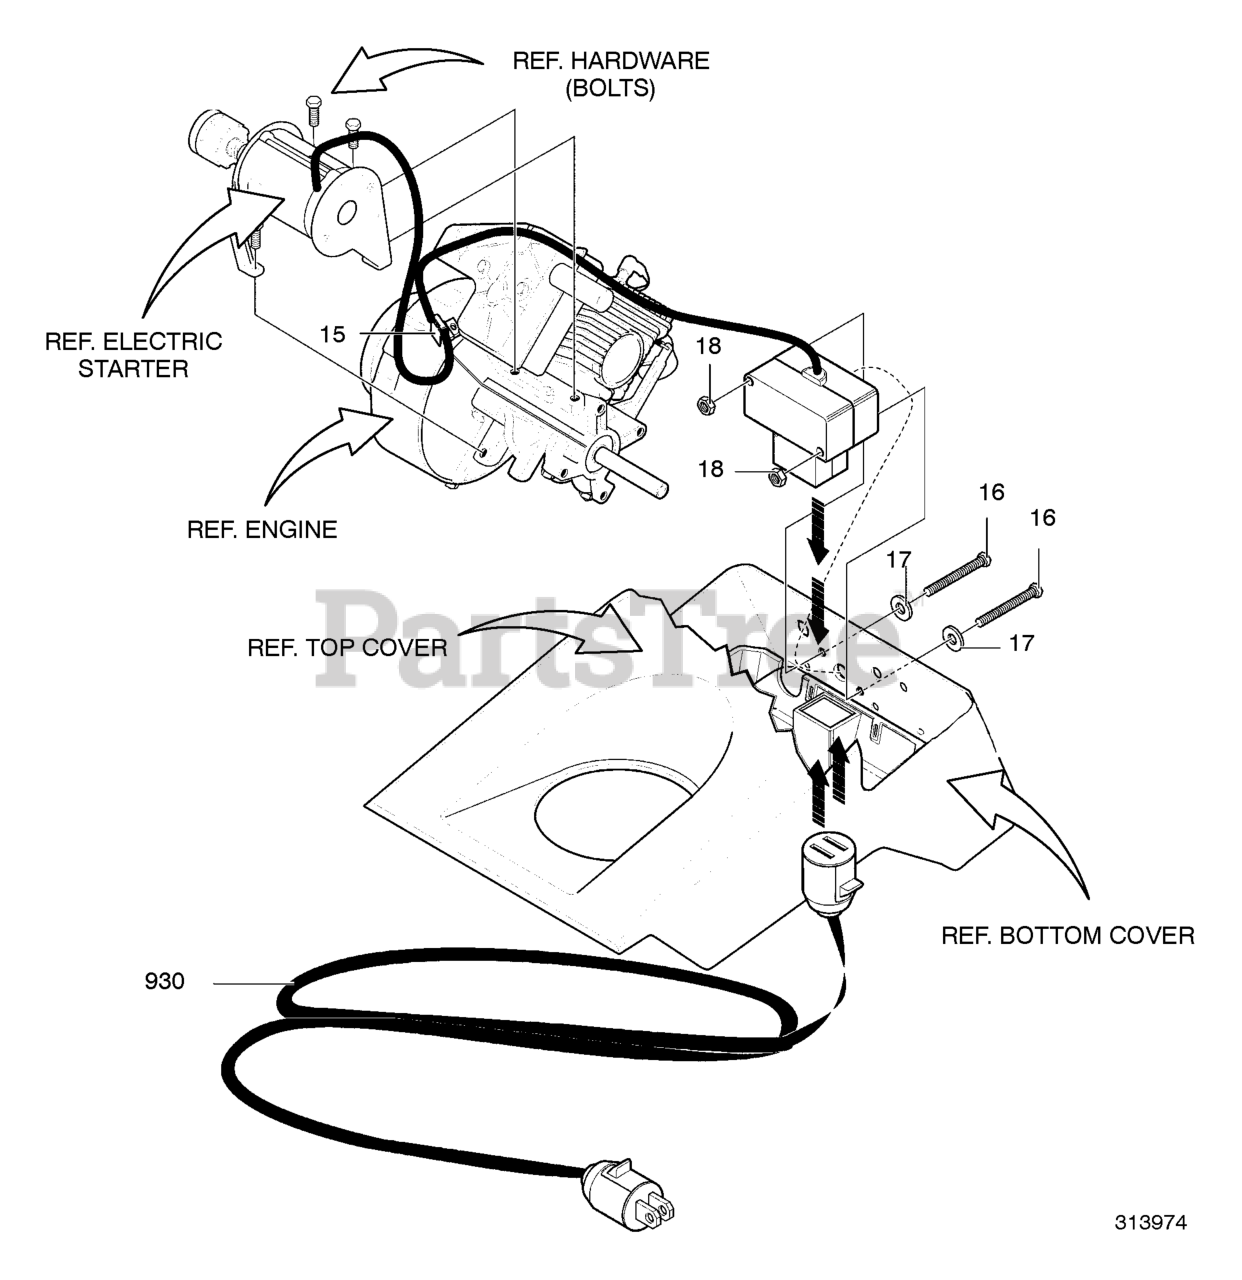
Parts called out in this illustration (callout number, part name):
15	STARTER CORD RETAINER
16	SCREW #8-32X3.00
17	WASHER, FLAT .188X.38X.040
18	NUT, #8-32X3.00
930	CORD EXTENSION
